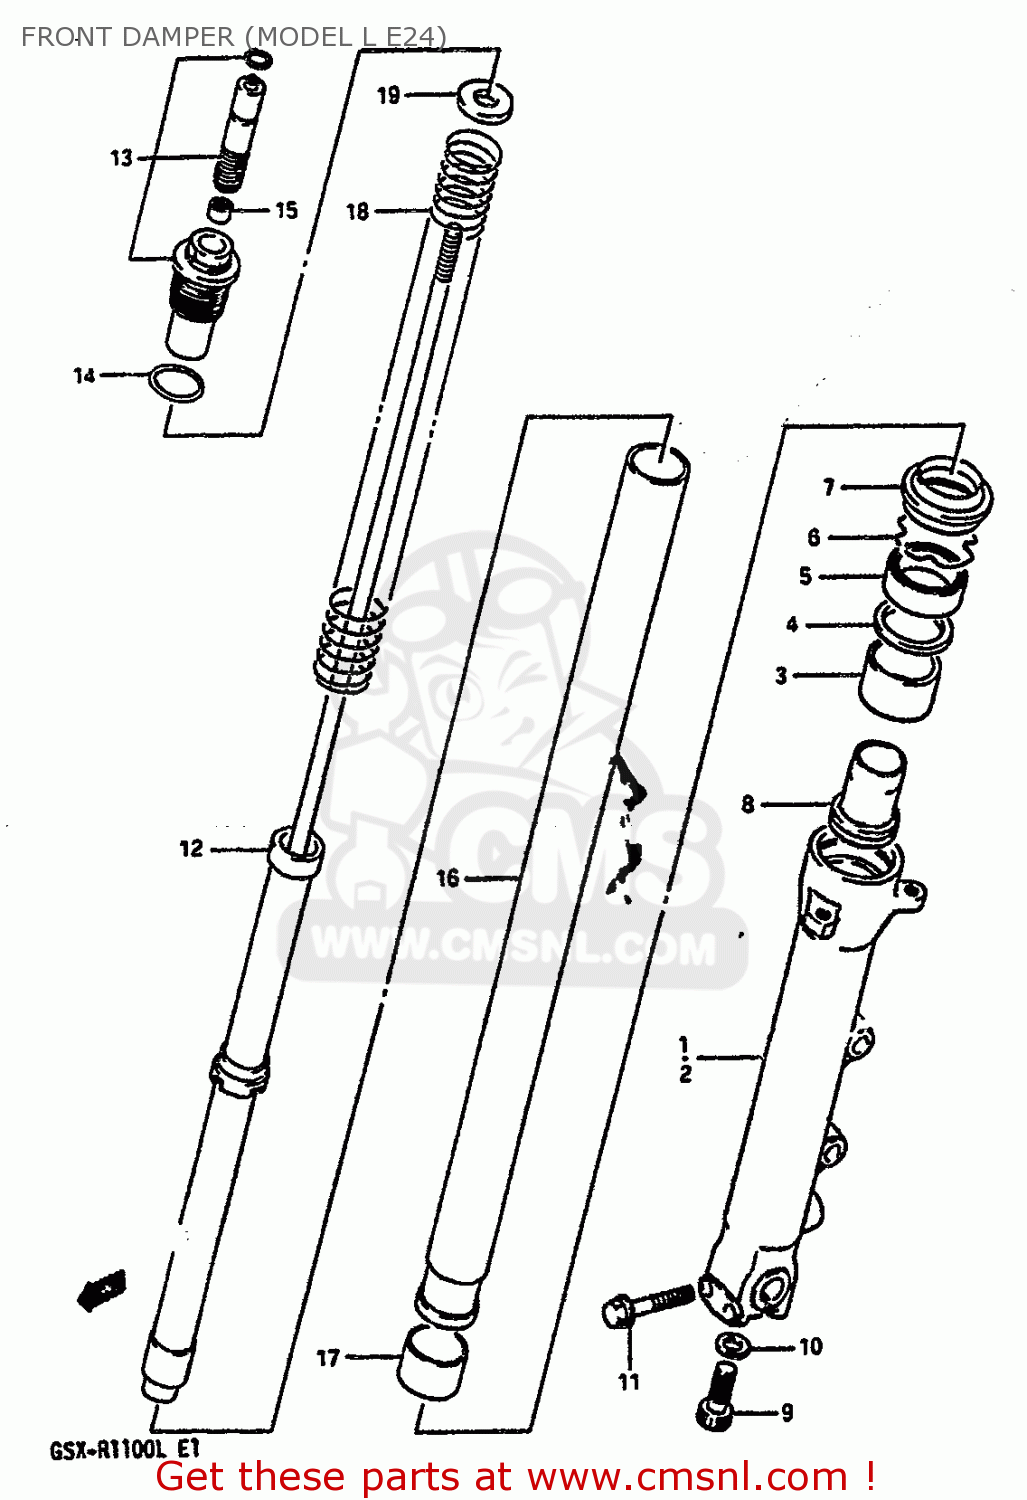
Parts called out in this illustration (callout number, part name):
1	TUBE,OUTER,R
2	TUBE,OUTER,L
3	METAL,SLIDE
4	WASHER
5	OIL SEAL,FRONT FORK
6	RING,STOPPER
7	SEAL,DUST
8	PIECE,OIL LOCK
9	BOLT,OIL LOCK PIECE,12X22
10	GASKET,CYLINDER (NAS)
11	BOLT,RH
12	CYLINDER,FRONT FORK
13	CAP ASSY,FORK
14	O RING
15	NUT,ROD
16	TUBE,INNER
17	PISTON
18	SPRING,FORK
19	WASHER,SPRING GUIDE
20	BOLT 8X12
